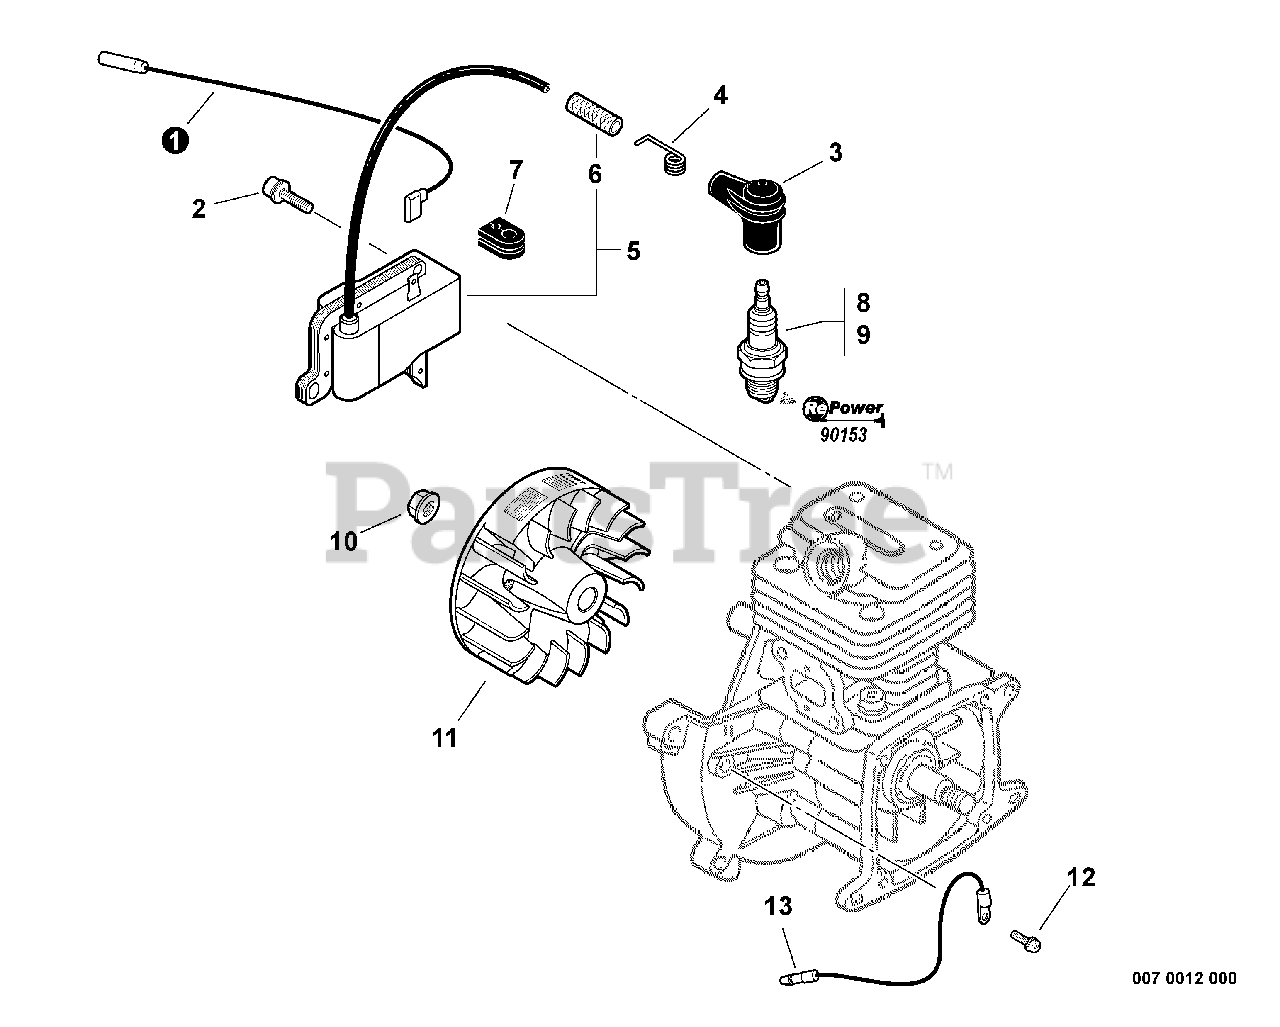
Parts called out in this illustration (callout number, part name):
1	LEAD - IGNITION 145 MM
2	BOLT 5×16
3	CAP, SPARK PLUG
4	TERMINAL, SPARK PLUG
5	COIL SET, IGNITION
6	TUBE, INSULATOR
8	SPARK PLUG - BPM8Y
9	SPARK PLUG - BPMR8Y
10	NUT, FLANGE M8
11	FLYWHEEL
12	SCREW 5×10
13	LEAD - GROUND
14	TUNE-UP KIT
